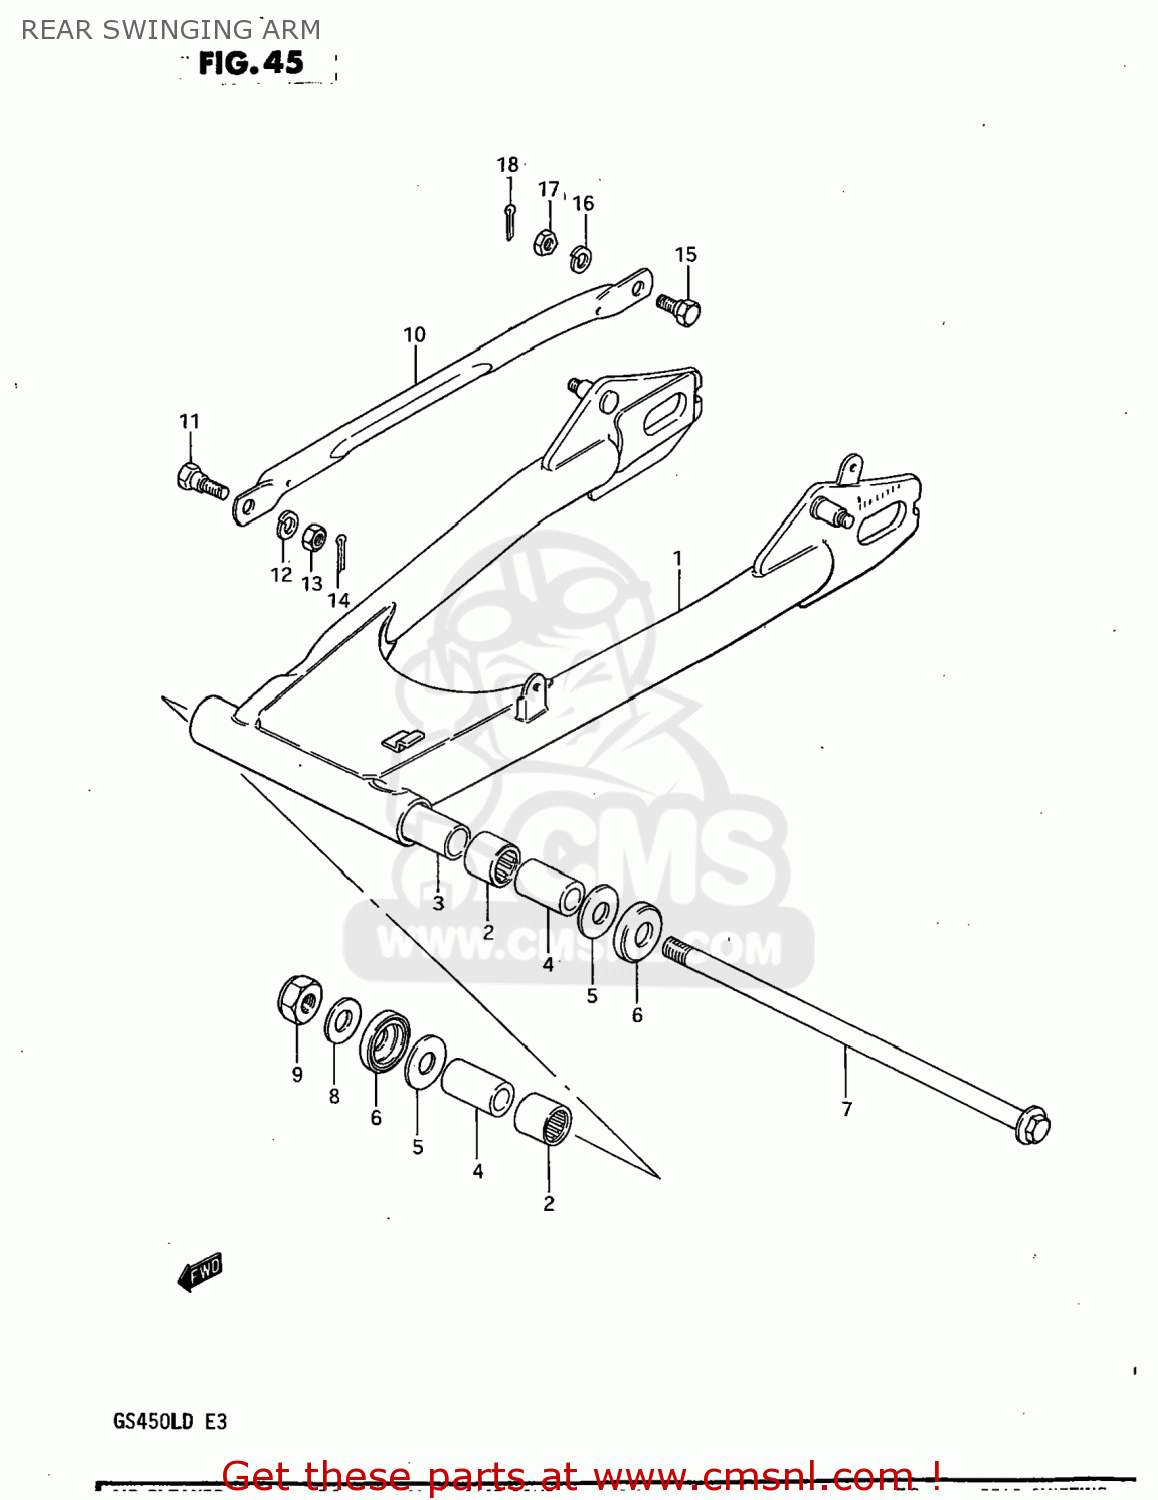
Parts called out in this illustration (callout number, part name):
1	ARM,REAR SWING
2	BEARING(22X29X30)
3	SPACER,SWINGINGARM CTR
4	SPACER,RR SWGARM PIVOT
5	WASHER(14.2X34X1)
6	CVR,RR SWGARM DUST SEAL(OD:40)
7	SHAFT,REAR SWING ARM
8	WASHER
9	NUT 14MM
10	LINK,REAR TORQUE
11	BOLT(10X24.5)
12	LOCK WASHER
13	NUT
14	PIN 20X20
15	BOLT(10X31)
16	LOCK WASHER
17	NUT
18	PIN 20X20
